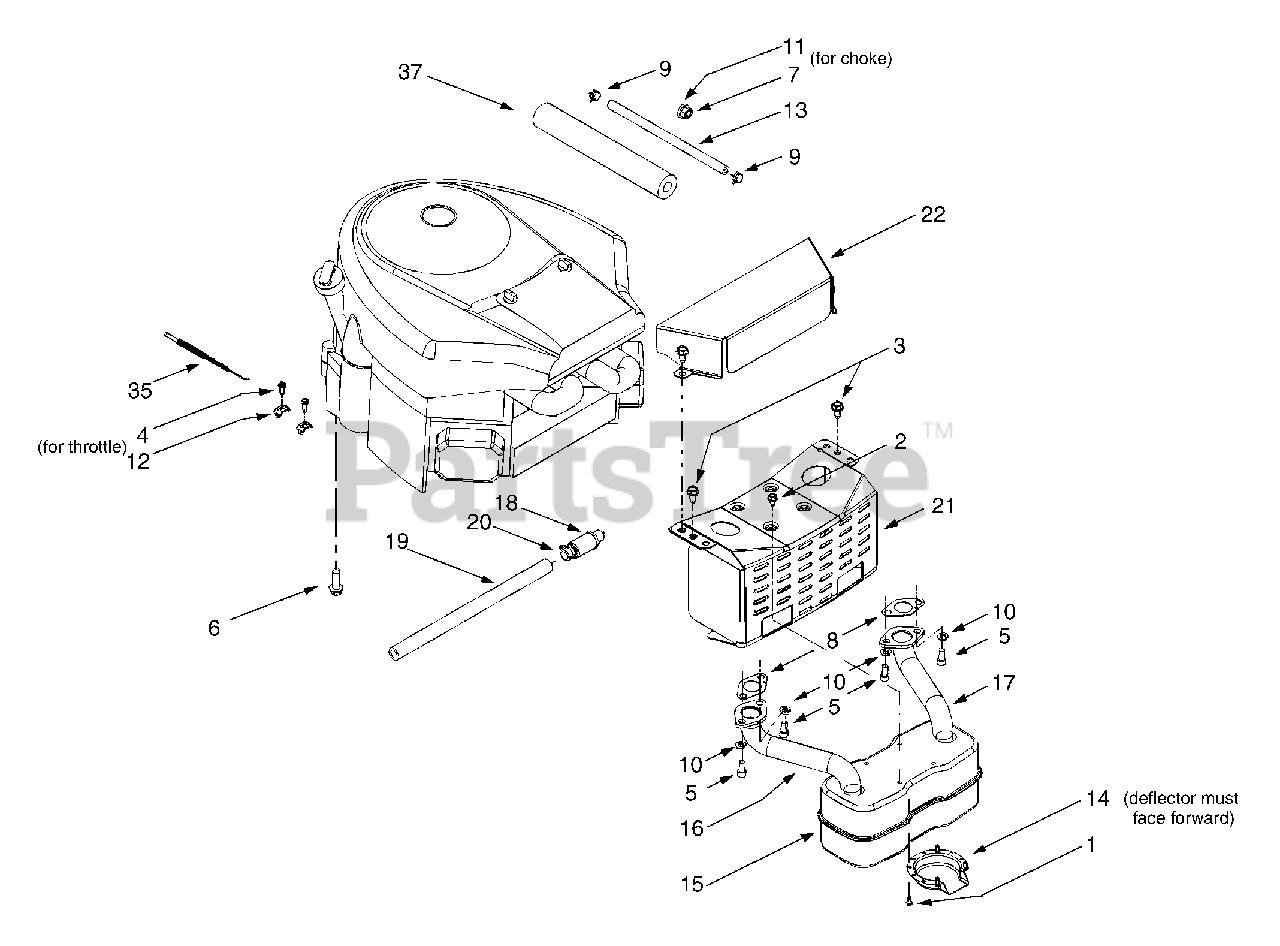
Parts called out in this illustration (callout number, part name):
1	Self-tapping Screw, #8-32 x .375
2	Self-tapping Screw, 1/4-20 x .5
3	Self-tapping Screw, 5/16-18 x .625
4	Screw, #10-32 x .625
5	Socket Cap Screw, 5/16-18 x .625
6	Self-tapping Screw, 3/8-16 x 1.25
7	Hex Nut, 3/8-16
8	Exhaust Gasket
9	Hose Clamp
10	Lock Washer, 5/16
11	Flat Washer, .406 x ..875 x .059
12	Casing Clamp
13	Fuel Line Hose
14	Muffler Deflector
15	Muffler, Twin Inlet
16	RH Exhaust Pipe
17	LH Exhaust Pipe
18	Oil Drain Valve
19	Oil Drain Hose
20	Oil Drain Cap
22	Engine Heat Shield
35	Throttle Cable
37	Foam
